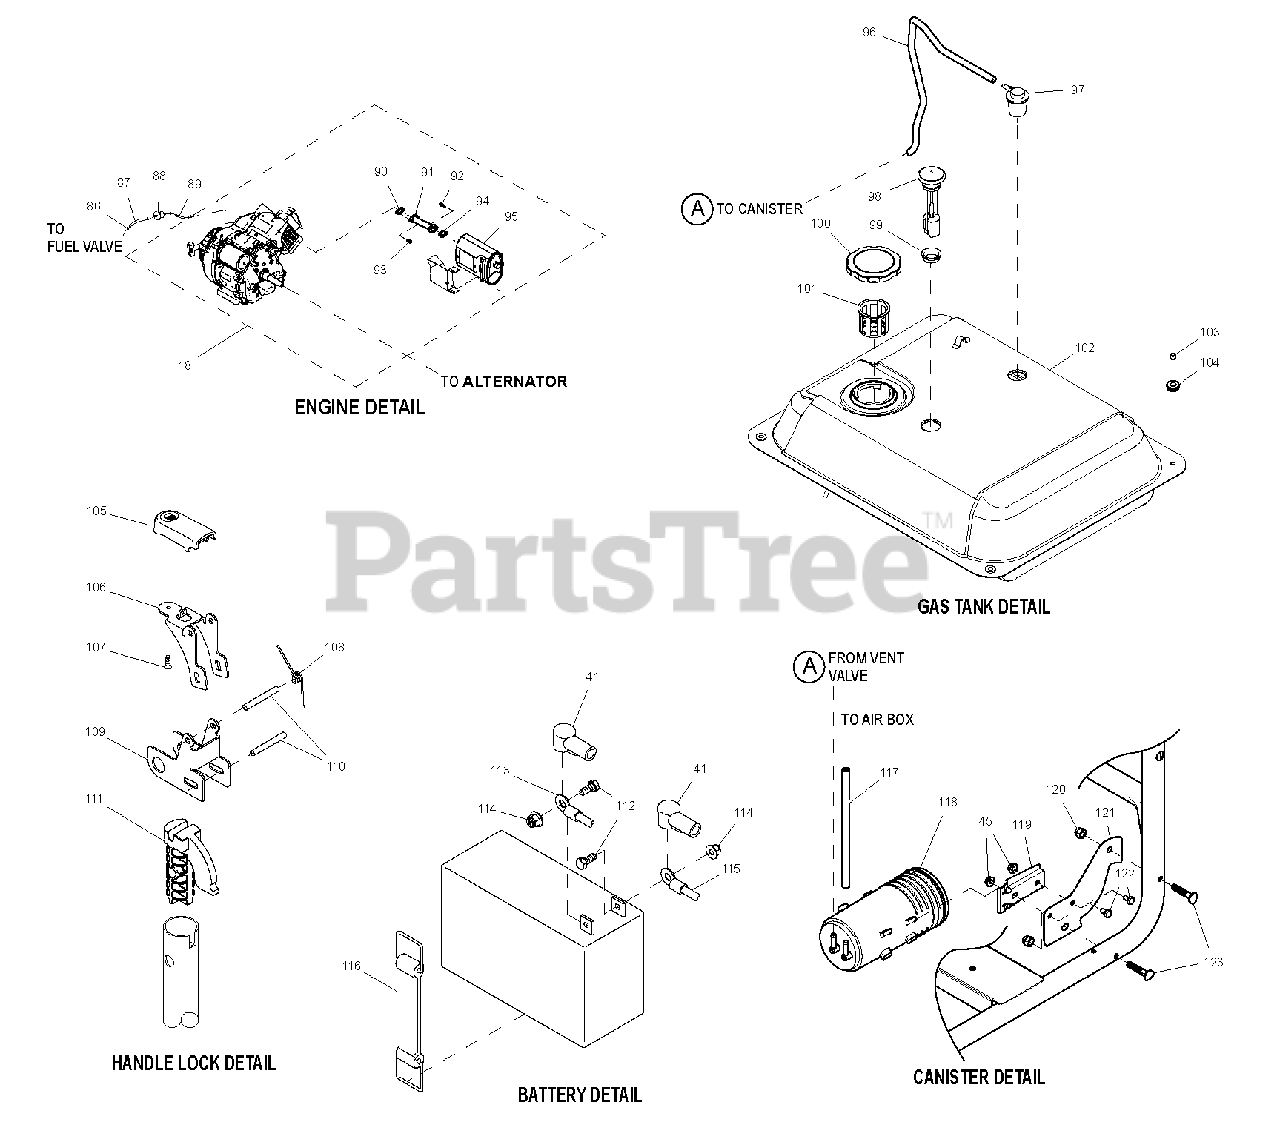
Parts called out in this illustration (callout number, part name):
86	CLAMP HOSE BAND SPRING .38
87	FUEL HOSE 4 ID X 8.5OD X 55MM
88	FUEL FILTER 389
89	FUEL HOSE 4 ID X 8.5OD X 80MM
90	GASKET' EXHAUST
91	MANIFOLD 410CC
92	SCREW SHC SEMS FLAT M8-1.25X20
93	SCREW SHC M8-1.25 X 20 C12.9
94	GASKET'EXHAUST PORT
95	MUFFLER GTH410 CARB
96	HOSE 11MM OD X 5.5MM ID X 33IN
97	ASSY' ROLL OVER SLANT VALVE
98	FUEL GAUGE'ROUND 6.5" LONG
99	GROMMET FUEL GAUGE ROUND
100	ASSY GAS CAP SEALED - BLACK
101	FILTER' FUEL
102	WELDMENT FUEL TANK XP CAL
103	INSERT' ANTI-CRUSH FOR TANKS
104	RUBBER MOUNT' 10.8 ID X 9 TALL
105	BUTTON LATCH RELEASE
106	LEVER' LATCH RELEASE
107	SCREW PFHP #8-16 X 1/2
108	SPRING TORSION' LATCH RELEASE
109	BRACKET' LATCH
110	PIVOT PIN' LATCH RELEASE
111	PLUG' FOLD DOWN HANDLE
112	SCREW HHC M5-0.8 X 12 C8.8
113	WIRE' #16 START SOL-STARTER XP
114	NUT FLANGE M5-0.8 NYLOCK
115	WIRE ASSY SOL TO BATT-POS
116	ASSEMBLY' BATTERY STRAP
117	HOSE 11MM OD X 5.5MM ID X 8IN
118	CARBON CANISTER'410CC ENGINE
119	BRACKET'CARBN CAN 410CC ENGINE
120	CAP NUT 5/16-18 ZBC
121	BRKT CARBN CANISTER MNT XP
122	SCREW HHC M6-1.0 X 10 C8.8
123	CURVED HEAD 5/16-18 X 1.625 LG
